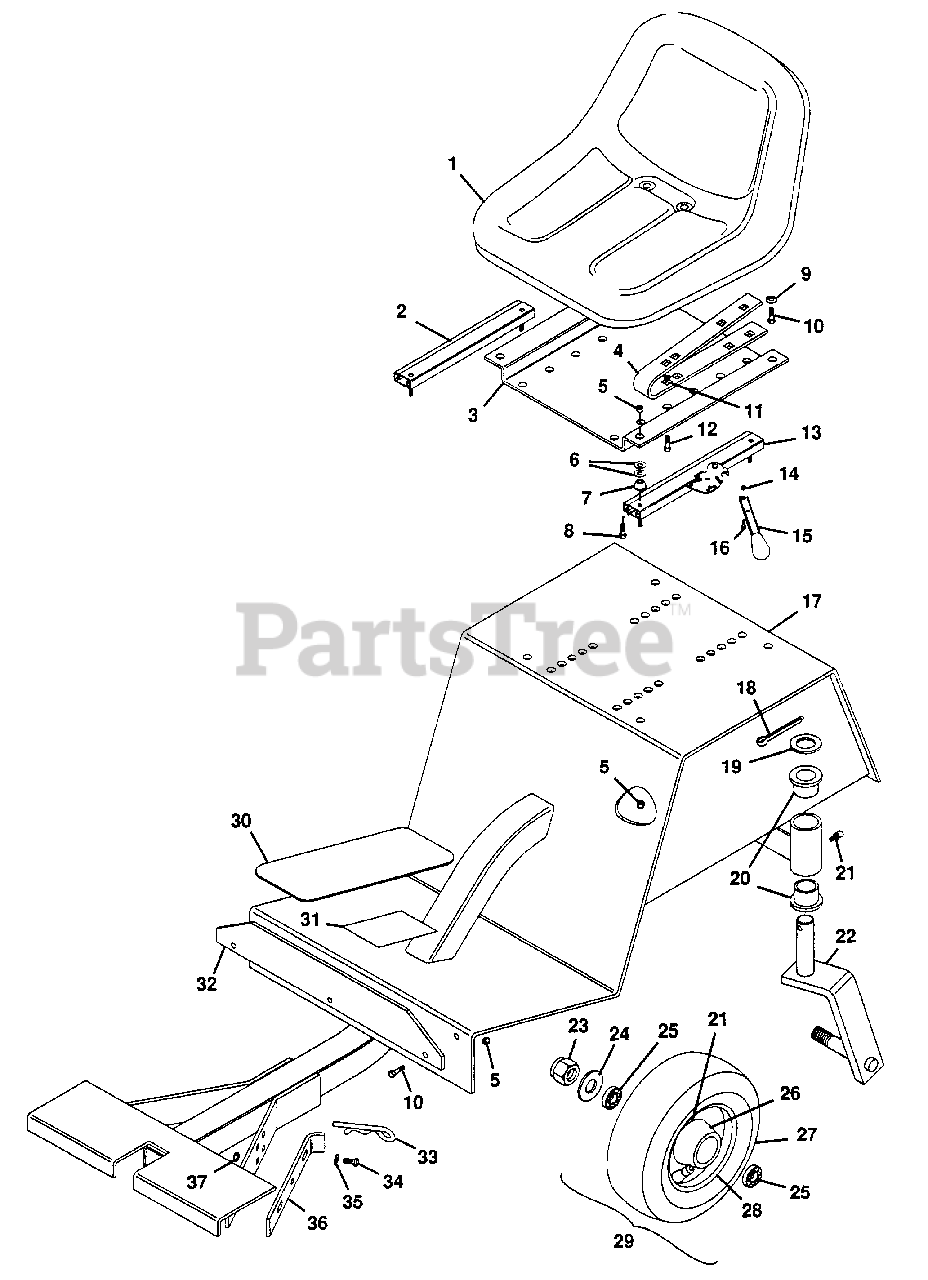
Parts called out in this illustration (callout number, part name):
1	Seat, High Back
2	Adjuster, Seat
3	Plate
4	Spring, Seat
5	Nut, Lock 5/16-18
6	Washer, Flat .344x.688x.065
7	Bushing, Flange Steel
8	Bolt, Hex 5/16-18x1.25
9	Washer, lock 5/16 Reg.
10	Bolt, Hex 5/16-18x.75
11	Nut, Lock 5/16-18
12	Bolt, Hex 5/16-18x1.00
13	Adjuster, Seat w/ Latch
14	Nut, Lock 10-24
15	Handle, Seat Adjuster
16	Screw, Mach 10-24x.625 P/Hd
17	Weldment, Sulky Frame
18	Pin, Cotter .187x1.62
19	Race, Bearing Thrust
20	Bushing, Pivot
21	Fitting, Lube 1/4-28
22	Weldment, Caster Fork
23	Nut, Lock 3/4-10
24	Washer, Flat .812x1.496x.134
25	Bearing
26	Wheel
27	Tire
28	Tube
29	Assembly, Wheel and Tire
30	Cover, Large Footboard
31	Decal, Sulky
32	Plate, Toe Guard
33	Pin, Hair
34	Bolt, Hex 3/8-16x1.125
35	Washer, Flat .375x1.125x.065
36	Strap, Sulky Latch
37	Nut, Lock 3/8-16
